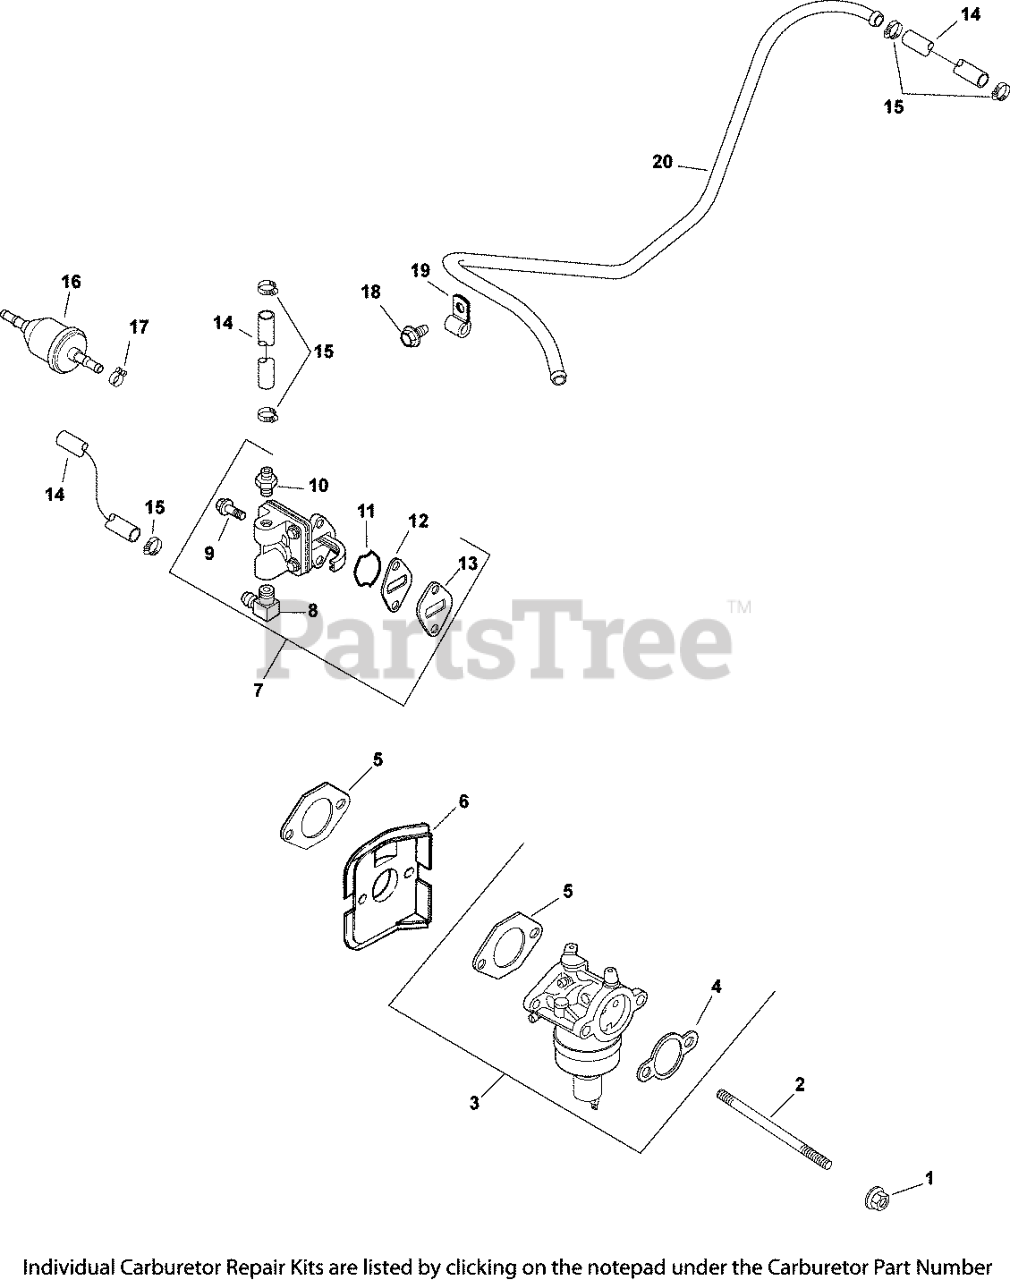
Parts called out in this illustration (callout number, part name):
1	NUT, FLG M6X1.0
2	STUD,M6X1.0X116
3	KIT, CARBURETOR w/GASKETS
4	GASKET, AIR CLEANER BASE
5	GASKET, CARBURETOR
6	DEFLECTOR, HEAT
7	KIT, FUEL PUMP
8	CONNECTOR, 90 DEG. HOSE
9	SCREW, LBD SKT M6x1.0x20-(#25086403S)
10	KIT, STRAIGHT FITTING
11	O-RING, FUEL PUMP
12	GASKET, FUEL PUMP
13	SPACER, FUEL PUMP
14	HOSE,LW PERM.FUEL 24.00"-USE 25 111 81-S
15	CLAMP, HOSE (KM)-USE 25 237 31-S
16	FILTER,FUEL 51 MICRON (FUEL PUMP)
17	CLAMP, BAND SPRING HOSE-(#2523737S)
18	SCREW, FLG THD FRM M5X.8X10
19	CLIP, TUBE & WIRING (KM)
20	LINE, FUEL
